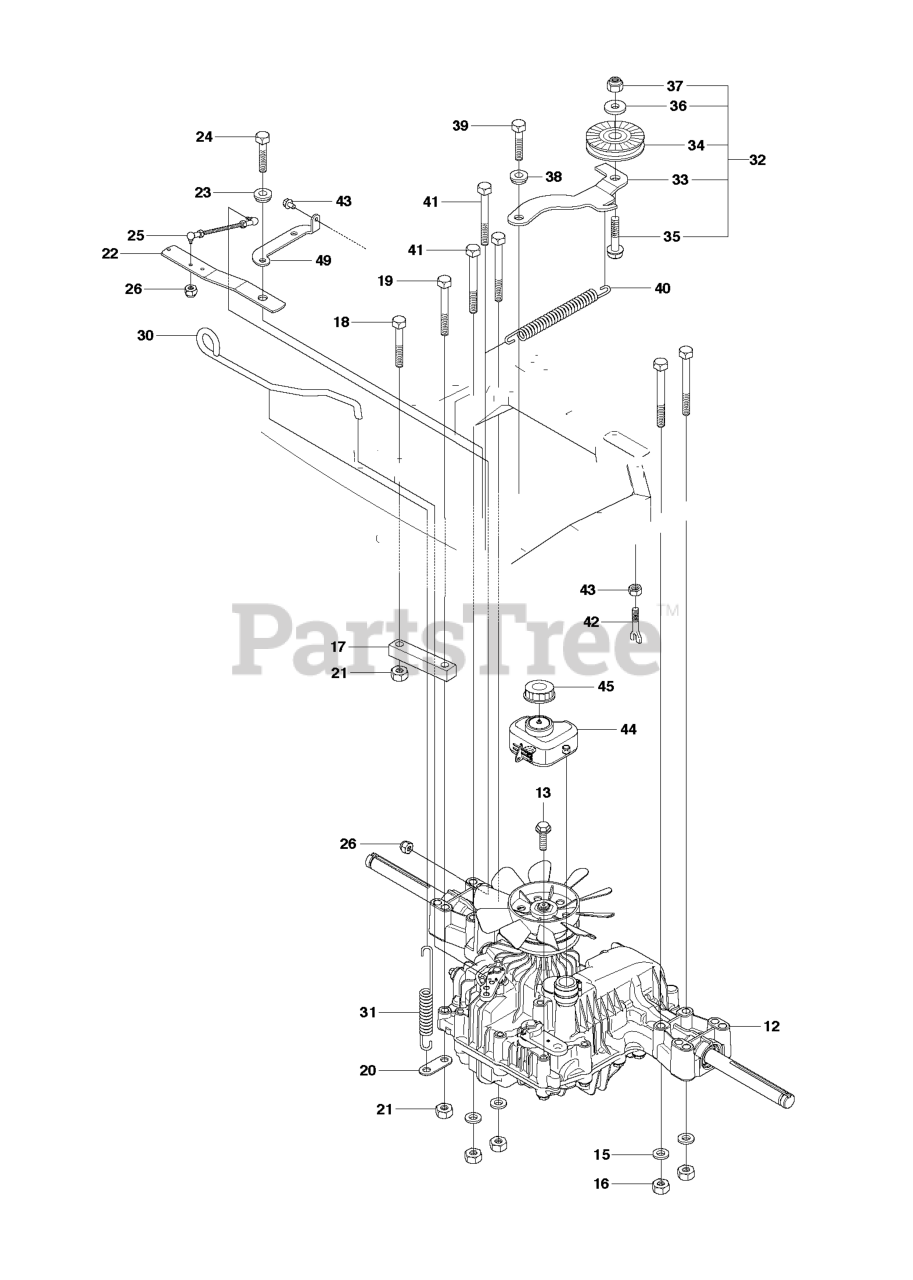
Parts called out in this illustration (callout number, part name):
12	HYDRAULMOTOR
15	WASHER BRB 8.4X17
16	NUT
21	NUT
23	WASHER
24	SCREW 8X20
26	LOCKNUT M5
33	TENSIONER
35	SCREW
37	LOCKNUT M8
38	WASHER
39	SCREW 8X20
43	NUT
